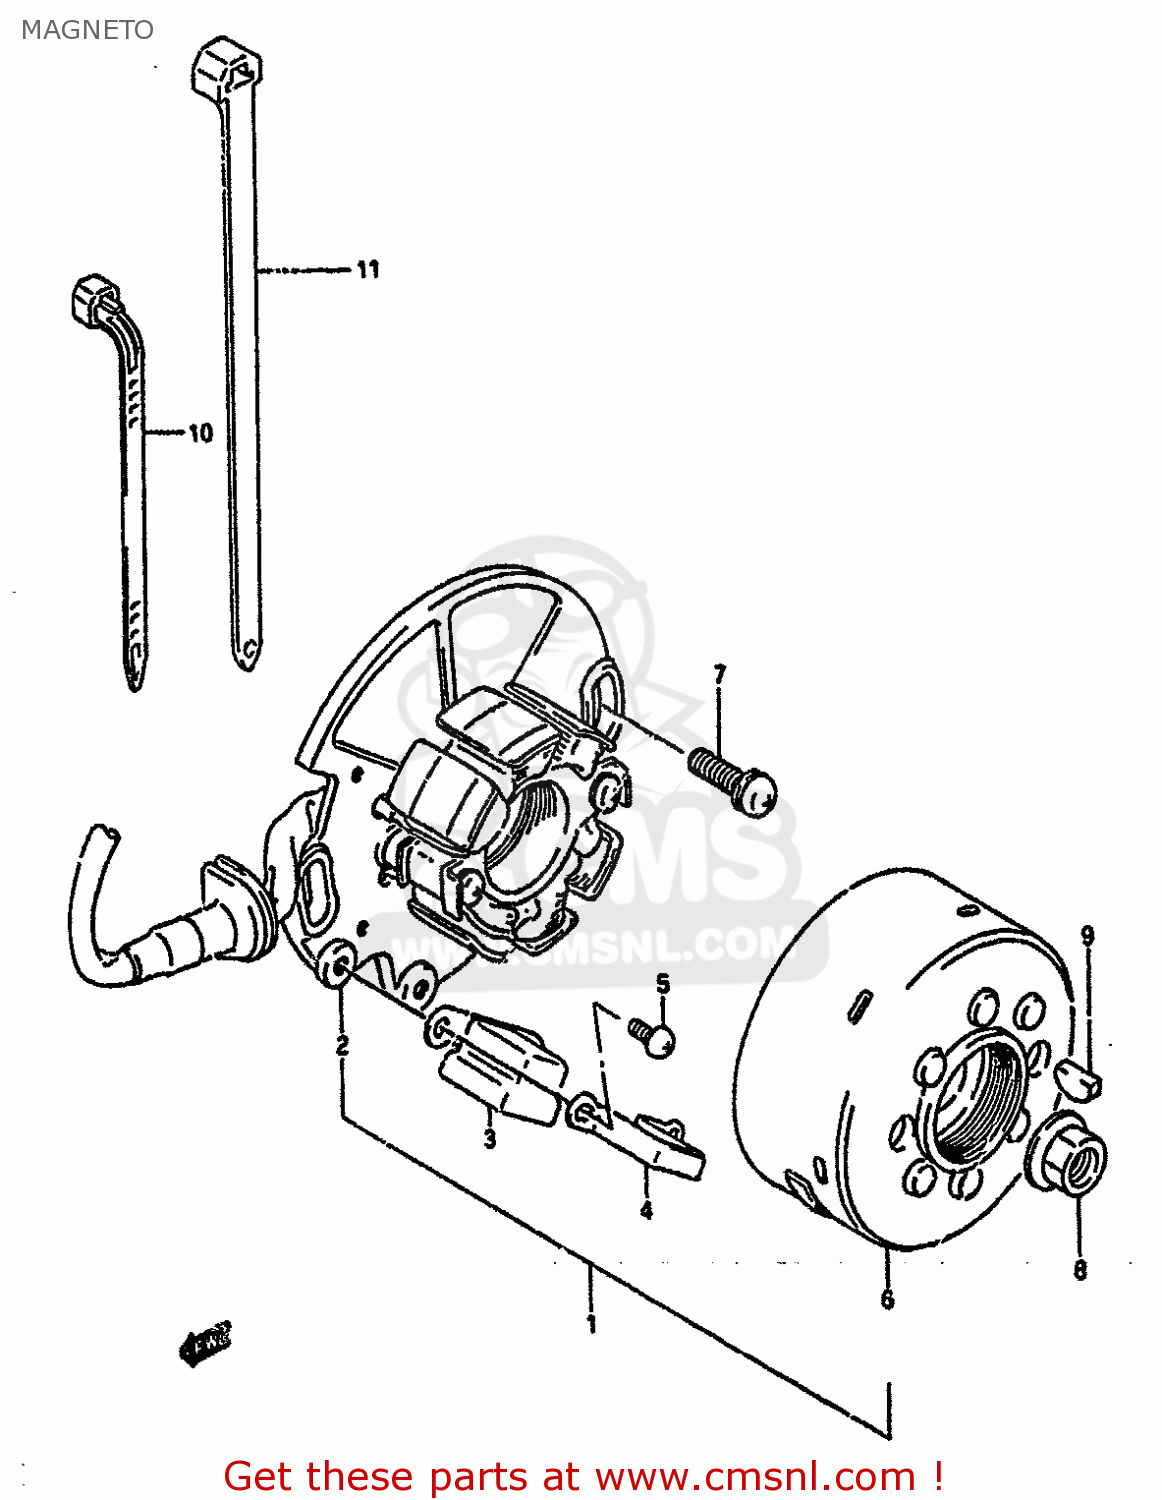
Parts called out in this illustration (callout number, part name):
1	MAGNETO ASSEMBLY
2	STATOR ASSEMBLY
3	COIL ASSEMBLY,PICK-UP
4	HOLDER,PICK UP COIL
5	SCREW
6	ROTOR
7	SCREW
8	NUT
9	KEY 4MM
10	CLAMP(L:125)
11	CLAMP
